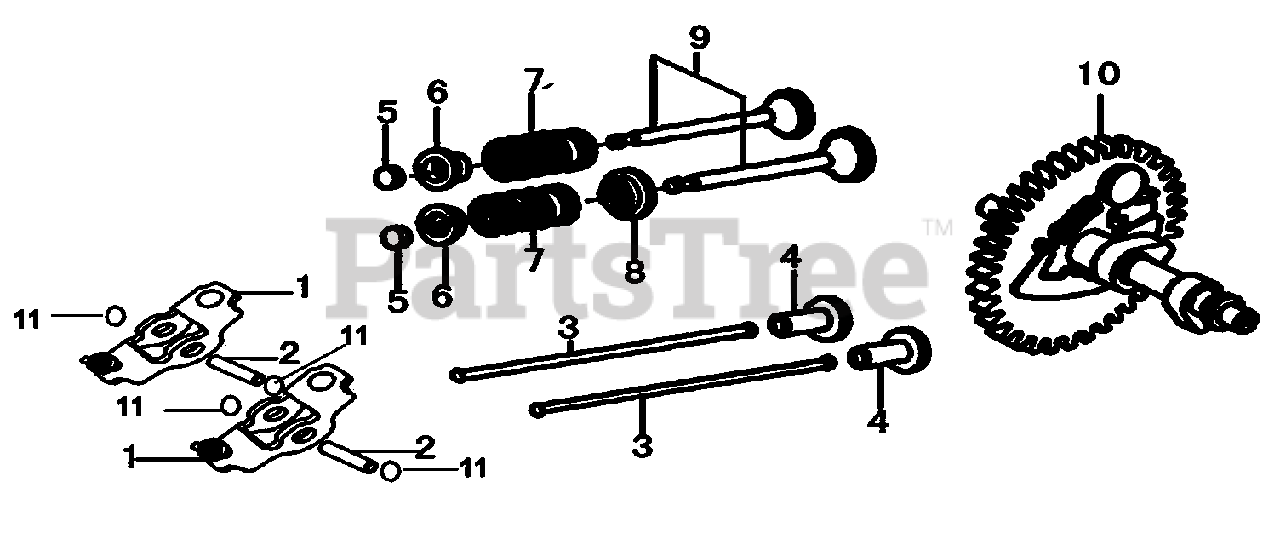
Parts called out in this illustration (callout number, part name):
1	ARM COMP.
2	VALVE ROCKER SHAFT
3	ROD, PUSH
4	LIFTER VALVE
5	ROTATOR, VALVE
6	RETAINER, VALVE SPRING
7	SPRING, VALVE
8	SEAL, GUIDE
9	VALVE COMP.
10	CAMSHAFT ASSY.
11	SPLIT WASHER
